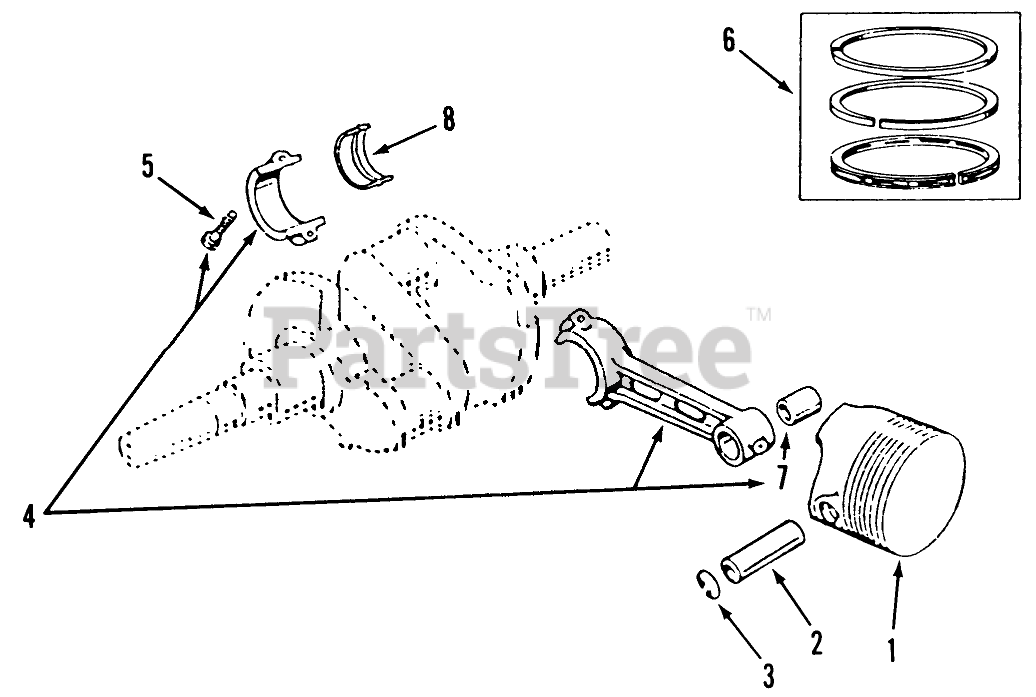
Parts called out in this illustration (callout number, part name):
1	Piston and Pin (includes Pin and Retaining Ring)
2	PIN - PISTON
3	Retaining Ring
4	Connecting Rod (Includes Bolts)
5	BOLT-PLACE
6	Piston Ring Set:
7	BUSHING-PISTON PIN
8	Connecting Rod Bearing Half:
